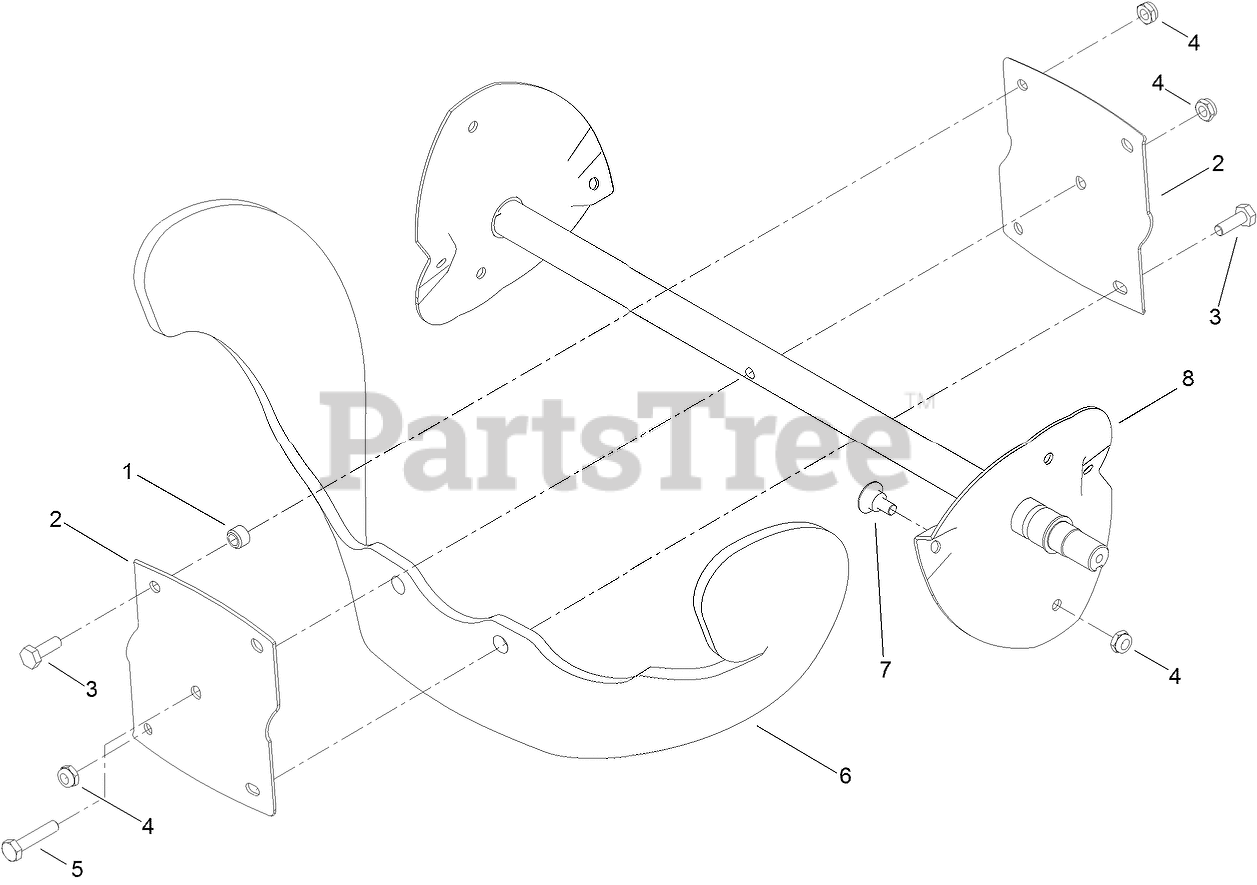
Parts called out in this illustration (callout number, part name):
1	SPACER-BLADE, ROTOR
2	HALF-ROTOR
3	SCREW-HH
4	NUT-LOCK, NI
5	SCREW-HH
6	BLADE-ROTOR
7	SCREW
8	ROTOR
